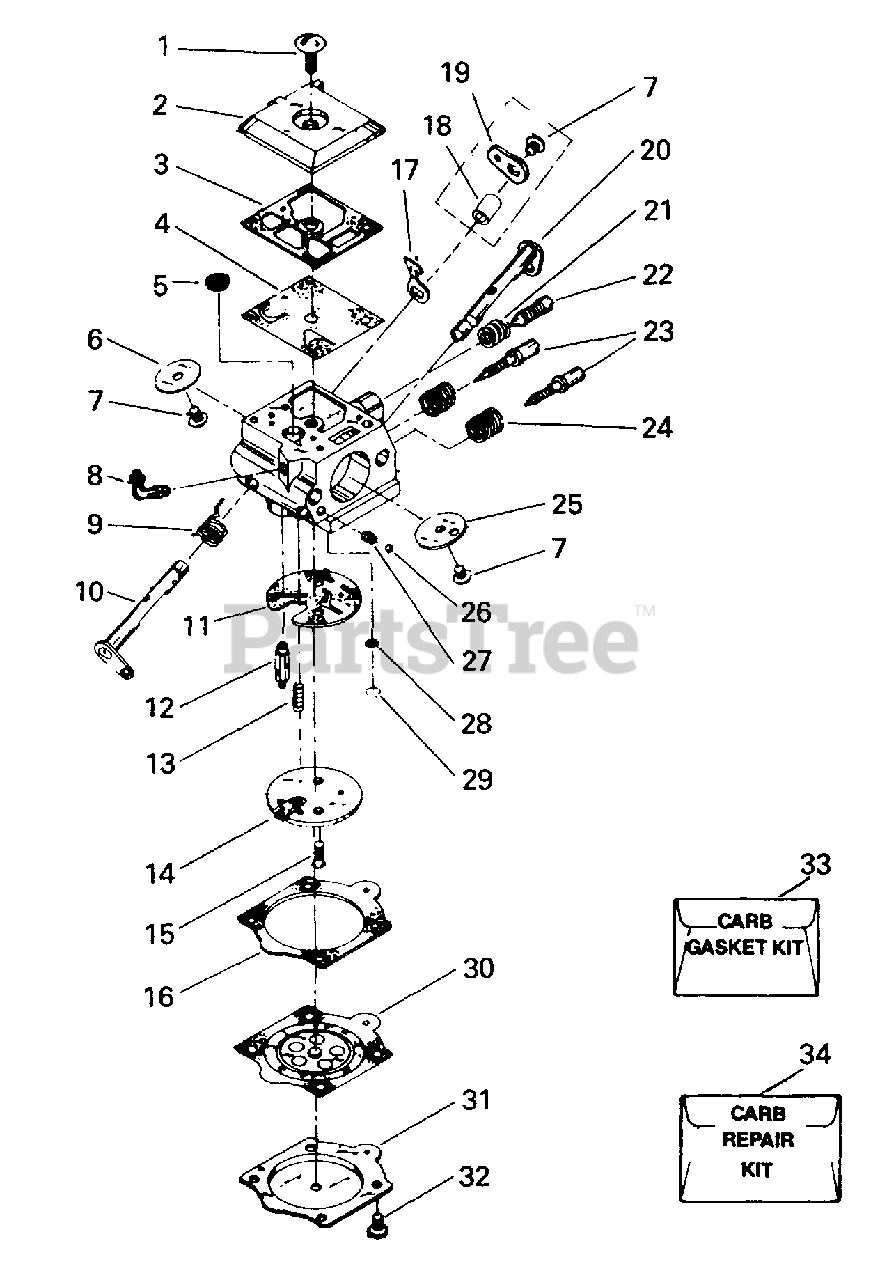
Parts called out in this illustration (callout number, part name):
1	Screw-Pump Cover
2	Cover-Fuel Pump
3	Gasket-Fuel Pump
4	Diaphragm-Fuel
5	Screen-Inlet
6	Valve-Throttle
7	Screw-Valve
8	Fitting-Inlet (Elbow)
9	Spring-Throttle Ret.
10	Shaft Ass'y.-Throttle
11	Gasket-Circuit
12	Valve-Inlet Needle
13	Spring-Mtrg.Lever
14	Plate Ass'y.-Circuit
15	Screw-Circuit Plate
16	Gasket-Mtrg.Diaphragm
17	Stop-Throttle
18	Bushing-Throttle Lv.
19	Lever-Throttle (Outer)
20	Shaft Ass'y.-Choke
21	Spring-Idle Screw
22	Screw-Idle Adj.
23	Needle-Hi & Lo
24	Needle Retainer Kit
25	Valve-Choke
26	Ball-Choke Friction
27	Spring-Choke Friction
28	Screen-Check Valve
29	Ring-Screen Retaining
30	Diaph.Ass'y.-Mtrg.
31	Cover-Mtrg.Diaphragm
32	Screw Ass'y.-Mtrg.Cover
33	Kit-Carb. Gasket
34	Kit-Carb. Repair-
